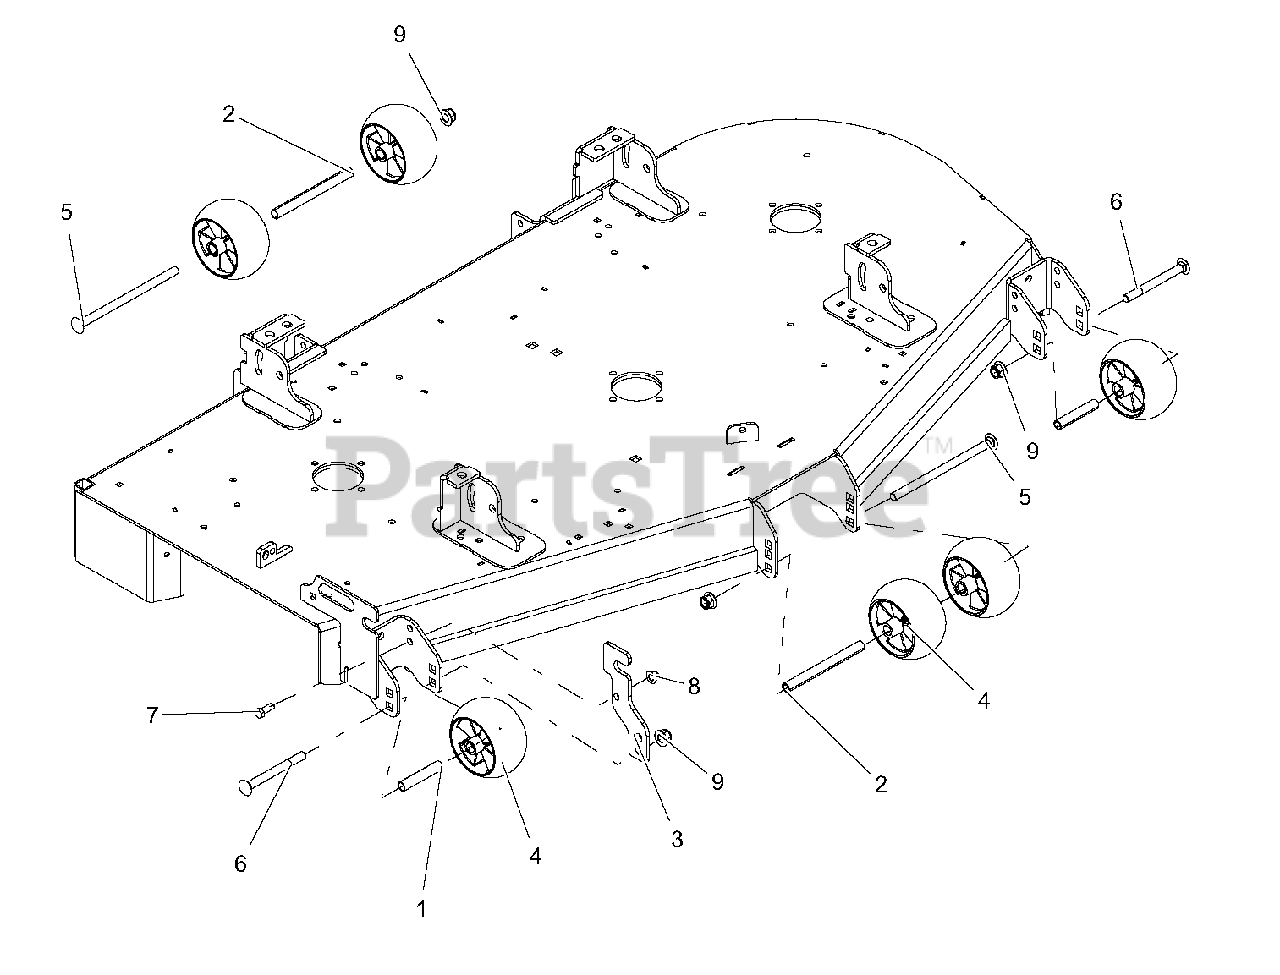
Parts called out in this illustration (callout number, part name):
1	SPACER, .510X.625X3.35
2	SPACER, .510X.625X6.70
3	CHUTE STORAGE BRACKET-RED
4	ANTI-SCALP WHEEL - 5X3 CTR
5	@BLT-RDHDSQNK .50-13X8.50 Y
6	BLT-RDHDSQNK .50-13X5.00 G5
7	BLT-HEX .38-16X1.00 GR5 YWZC
8	NUT-LK-NYL-FLG .38-16 YWZC
9	NUT-LK-NYL-FLG .50-13 YWZC
